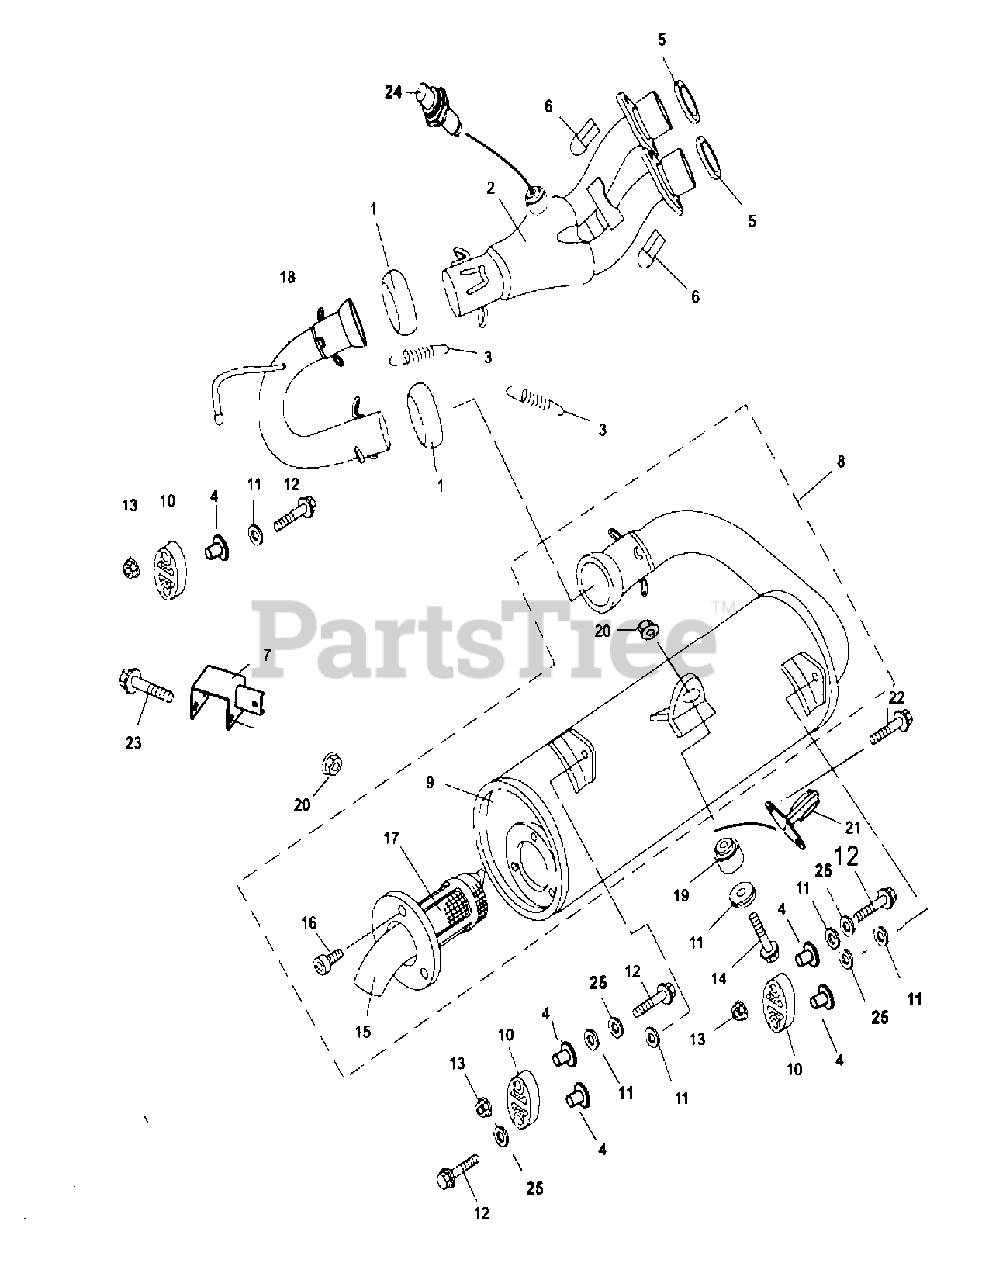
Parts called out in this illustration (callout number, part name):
1	Muffler Sealing Boot
2	Exhaust Pipe I(EFI Engine)
3	Tension Spring XI
4	Bushing 6.5×9×22×17
5	Exhaust Pipe Gasket
6	Nut M8×32
7	Exhaust Pipe Hanging Clamp
8	Muffler
9	Muffler
10	Damping Pad, Mufflier
11	Stainless Steel Heat Insulation Pad
12	Hexagon Flange Bolt M6×30
13	Hexagon Flange Nut M6
14	Hexagon Flange Bolt M8×45
15	End of Exhuast Pipe
16	Hexagon Socket Head Bolt M6×20
17	Fireproofing Net,Muffler
18	Exhaust Pipe II(without Rear Differntial Status)
19	Suspension Bushings
20	Hexagon Flange Lock Nut M8 (Metallic Insert)
21	Muffler Fixed Seat
22	Hexagon Flange Bolt M8×20
23	Hexagon Flange Bolt M8×70
24	Oxgyen Sensor Assy(EFI)
25	Spring Washer -6
